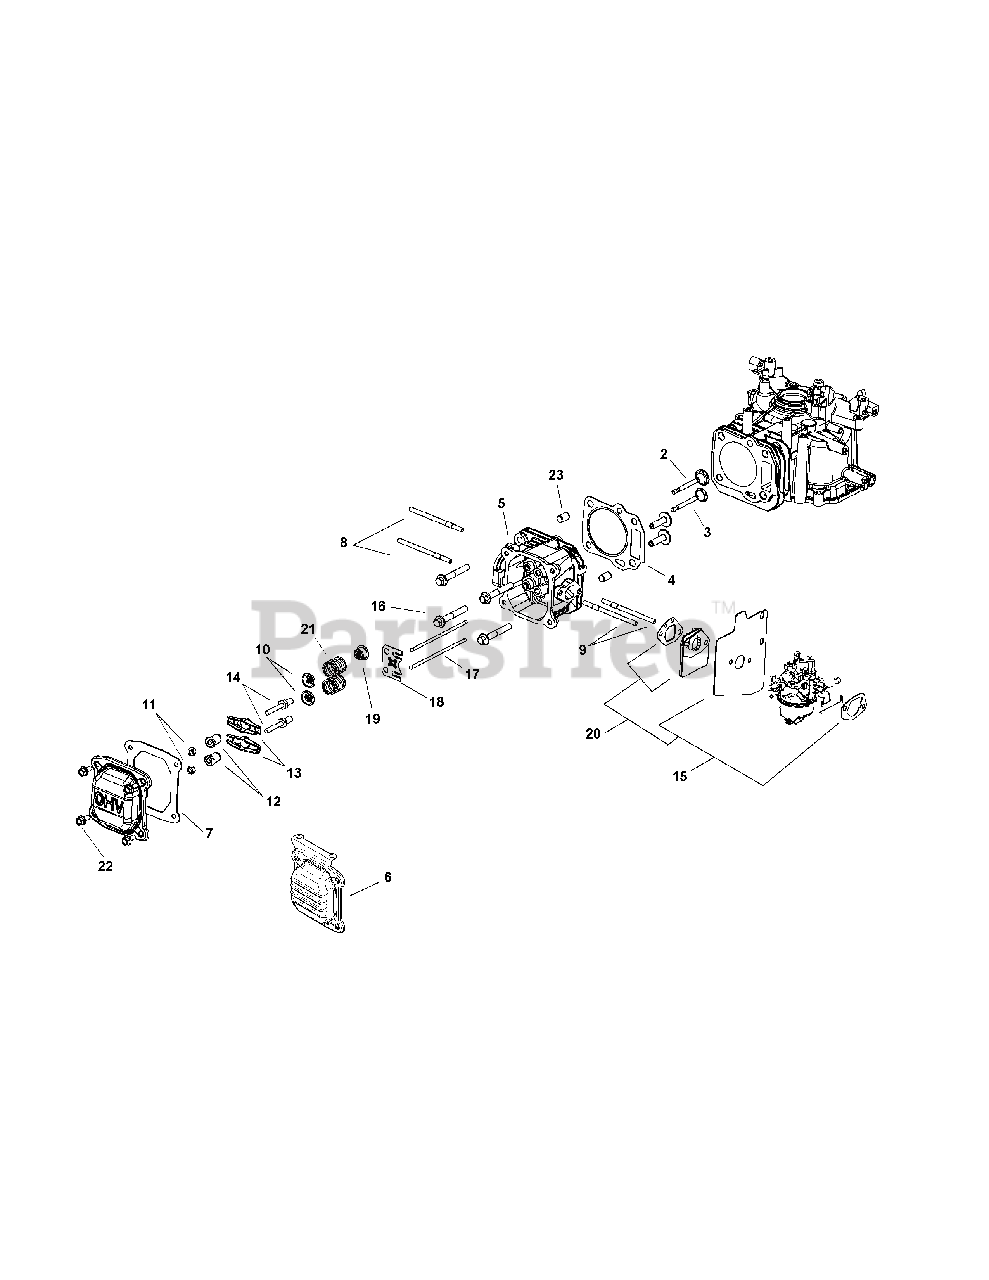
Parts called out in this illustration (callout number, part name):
1	Valve Train Kit
3	Exhaust Valve
4	Head Gasket Kit (Inc. Muffler Gasket)
5	Cylinder Head Kit
6	Valve Cover Kit
7	Valve Cover Gasket
8	Stud Kit (M6)
9	Stud, M6 x 1.0 x 93
10	Valve Spring Retainer
12	Rocker Arm Pivot
14	Rocker Arm Stud
15	Gasket Kit
16	Hex Flange Screw, M8
18	Push Rod Guide Plate
19	Valve Stem Seal
20	Carburetor Spacer
22	Hex Flange Screw, M6
23	Cylinder Head Dowel
